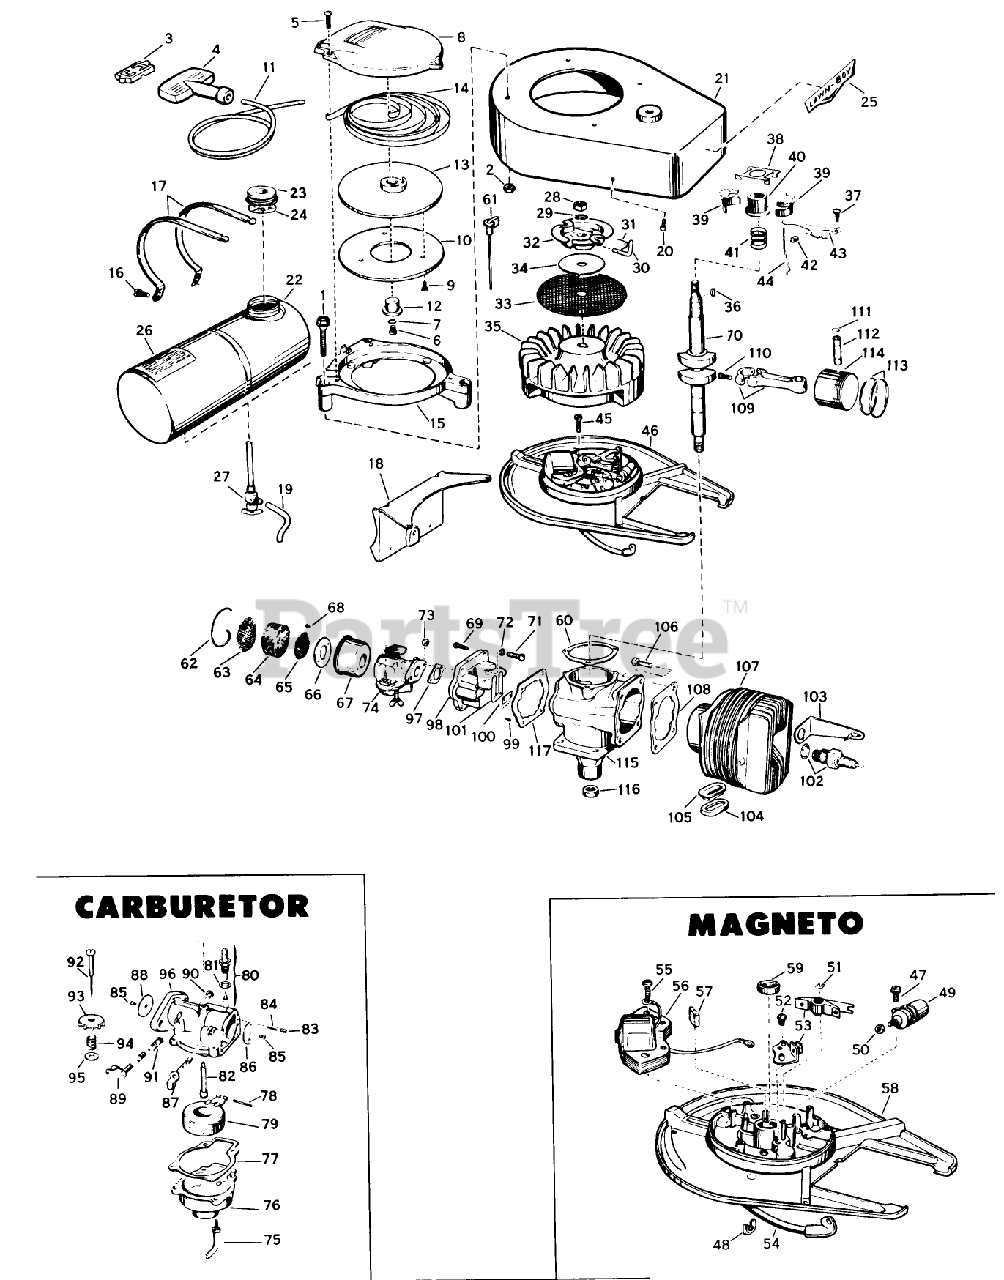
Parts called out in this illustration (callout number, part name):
14	RECOIL SPRING
15	Base-Starter
20	SCREW S
23	Gas Cap
26	Decal-Instruction
27	VALVE&SCREEN SM
30	PIN - STARTER
40	COLLAR S
41	Spring-Governor
42	WEAR BLOCK S
43	GOVERNER LEVER AY
44	GOVERNOR ROD S
51	Spring Clip-Breaker Post
53	BREAKER AY. S
57	Oiler Wick
60	GASKET S
64	ELEMENT
66	BACK-UP PLATE
69	SCREW S
70	Crankshaft
73	STOP NUT
85	Screw-Choke Disc
91	SPRING
92	NEEDLE AY. S
94	Spring-Ndl. Adj.
97	GASKET S
100	PLATE-BACKUP, REED
102	Spark Plug
107	Cylinder Sleeve Assembly
110	Screw-Connecting Rod
113	Ring-Piston
